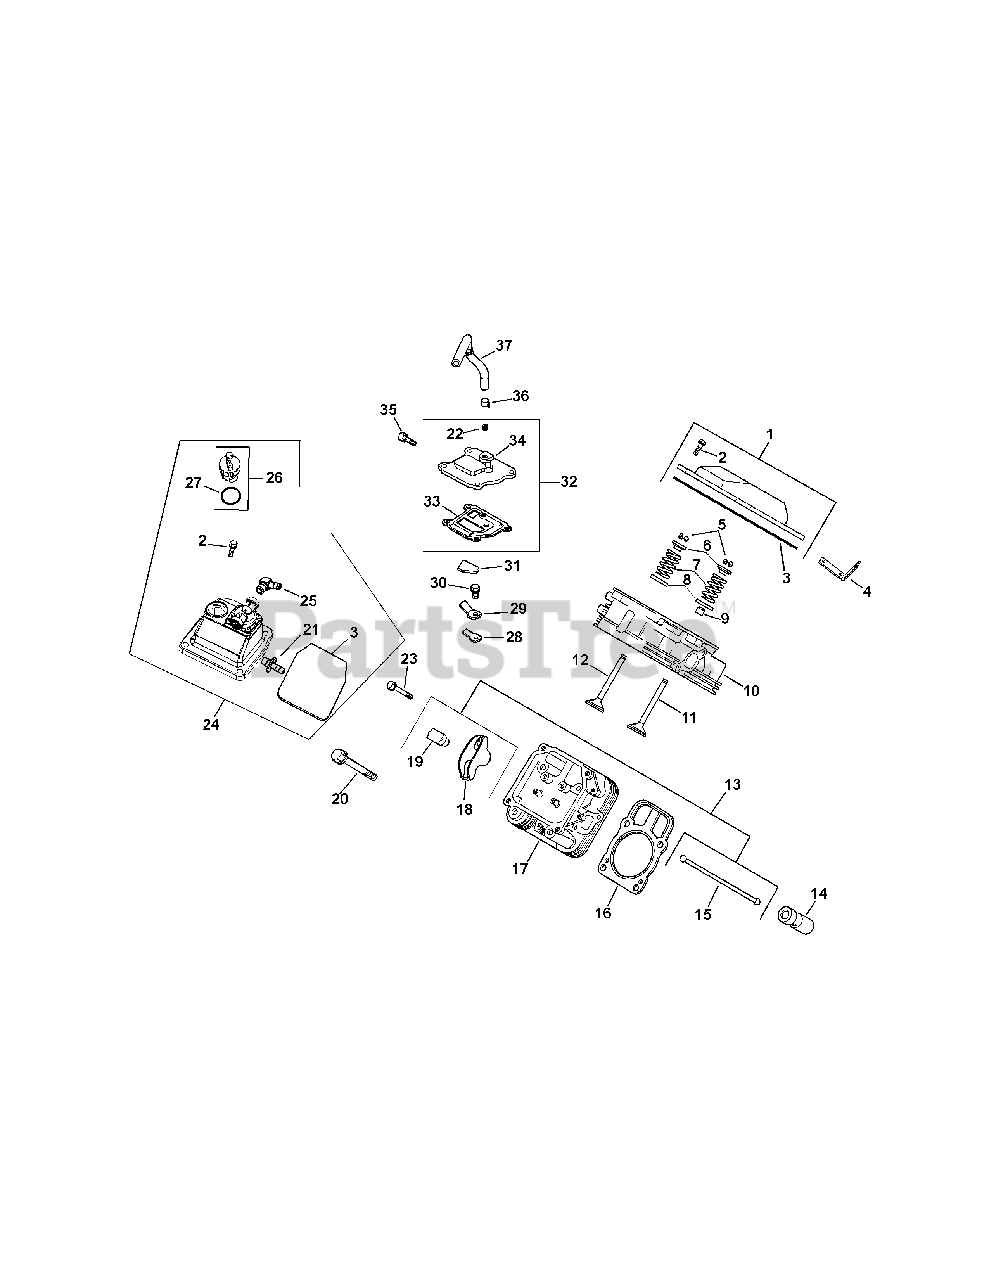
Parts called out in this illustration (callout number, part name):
1	Kit, oil fill rocker cover (Incl. 2,3)
2	Screw, hex flange M6x1.0x30 (4)
3	O-Ring, valve cover
4	Strap, lifting (2)
5	Kit, retainer (2)
6	Cap, valve spring (2)
7	Spring, valve (2)
8	Retainer, spring (2)
9	Seal, valve stem
10	Head assembly, #1 cylinder
11	Valve, intake (Std.)
11	Valve, intake (.25)
12	Valve, exhaust (Std.)
12	Valve, exhaust (.25)
13	Kit, valve train (Incl. 15,18,19)
14	Lifter, valve (4)
15	Rod, push (2)
16	Kit, cyl head gskt (Incl. 21,22) (2)
17	Head assembly, #2 cylinder
18	Arm, rocker (2)
19	Pivot, rocker arm (2)
20	Screw, Flg, M10x1.5x90 (8)
21	Fitting, 45°
22	Plug, ctsk pipe 1/8"
23	Screw, hex flange M6x1.0x34 (2)
24	Kit, fuel pump (Includes 2, 3, 21,25-27)
25	Fitting, 90° (2)
26	Cap assembly, oil fill (Incl. 27)
27	O-Ring, dipstick
28	Reed, breather
29	Retainer, reed
30	Screw, hex. flange M5x0.8x10
31	Filter, breather
32	Kit, breathe (Includes 33,34)
33	Gasket, breather
34	Cover, breather
35	Screw, hex flange M6x1.0x20 (4)
36	Clamp, hose
37	Hose, breather
